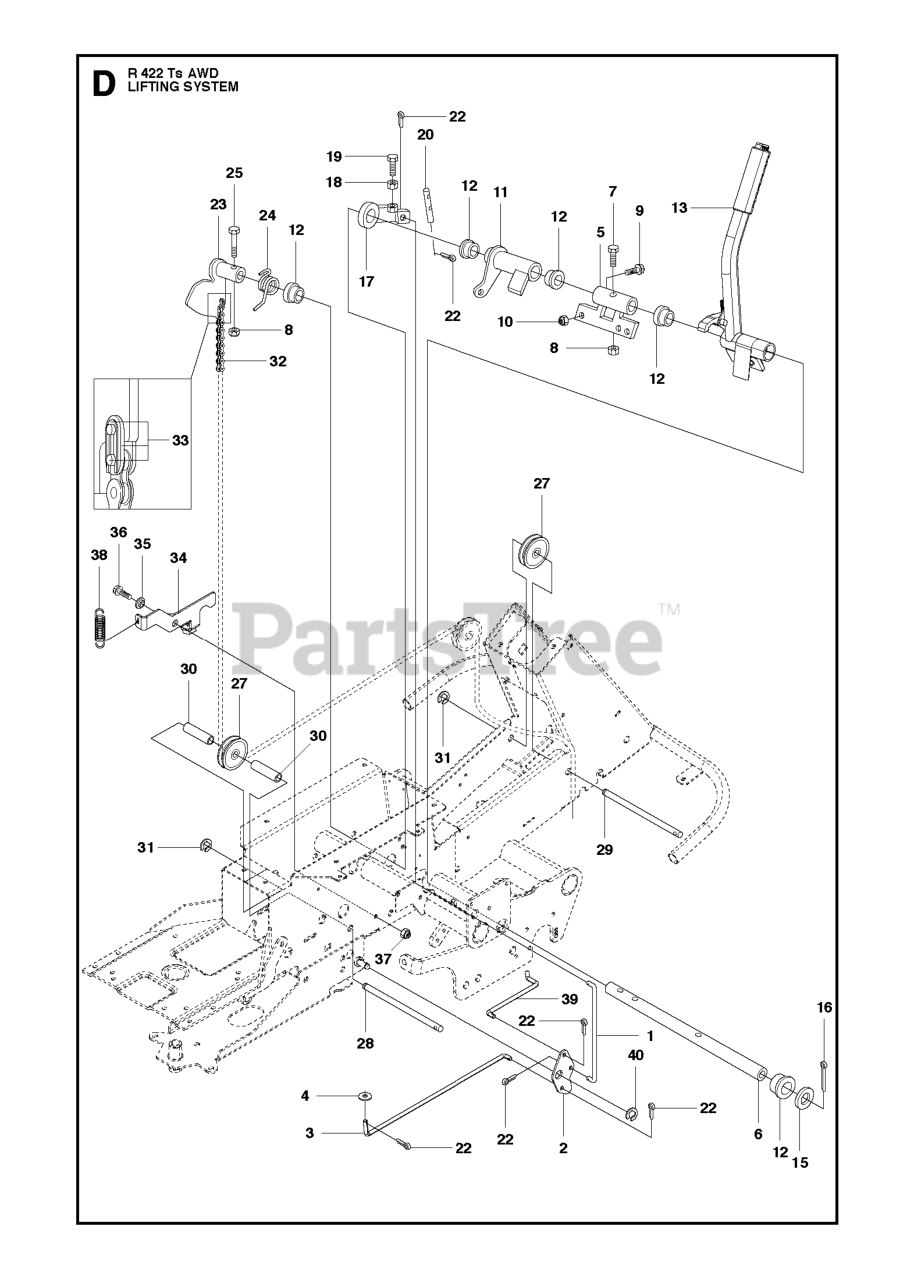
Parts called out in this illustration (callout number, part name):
10	NUT
12	BEARING FLANGE
13	LIFTING LEVER ASSY
17	LEVER CLUTCH
35	WASHER
36	BOLT
37	LOCKNUT M8
40	RETAINING RING
